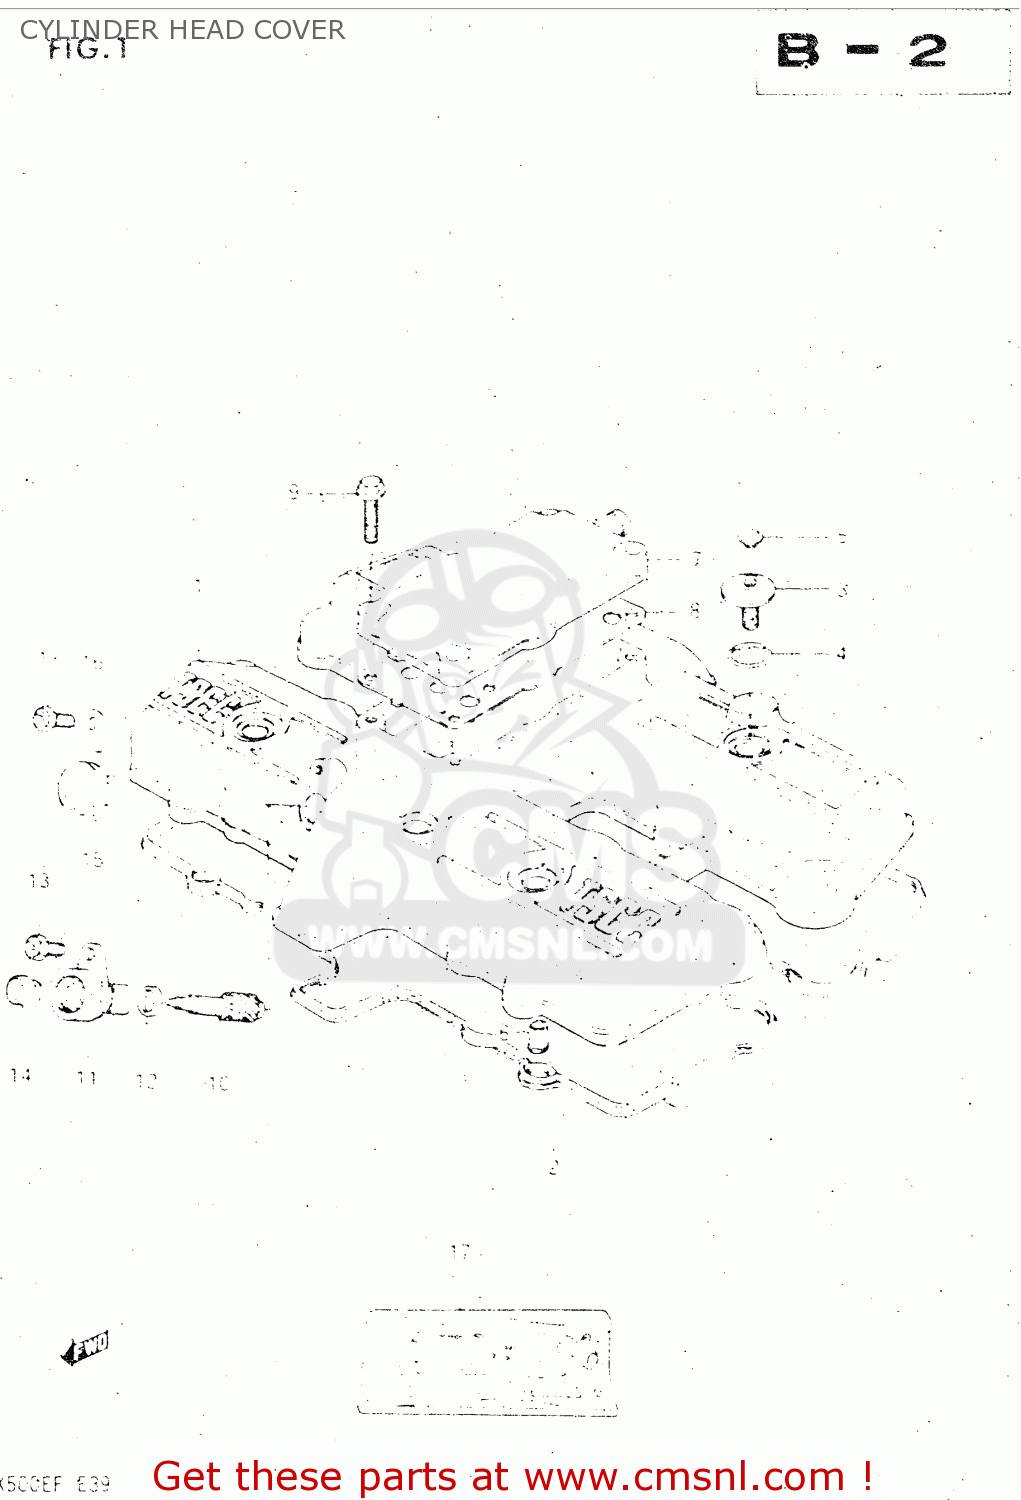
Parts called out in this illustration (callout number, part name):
1	COVER,CYLINDER HEAD
2	GASKET,CYL HEAD COVER (NAS)
3	BOLT(7X5.5)
4	O RING(D:1.9,ID:14.5)
5	CAP(OD:10)
6	PIN
7	COVER,BREATHER
8	GASKET (MCA)
9	BOLT
10	GEAR,TACHOMETER DRIVEN
11	SLEEVE,TACHOMETER DRIVE GEAR
12	SEAL,TACHOMETER DRIVEN
13	SCREW(5X12)
14	SEAL,OIL(5X12X8)
15	PLUG,TACH GEAR SLEEVE HOLE
16	PLATE,TACH DRIVE GEAR SLEEVE
17	GASKET SET (MCA)
